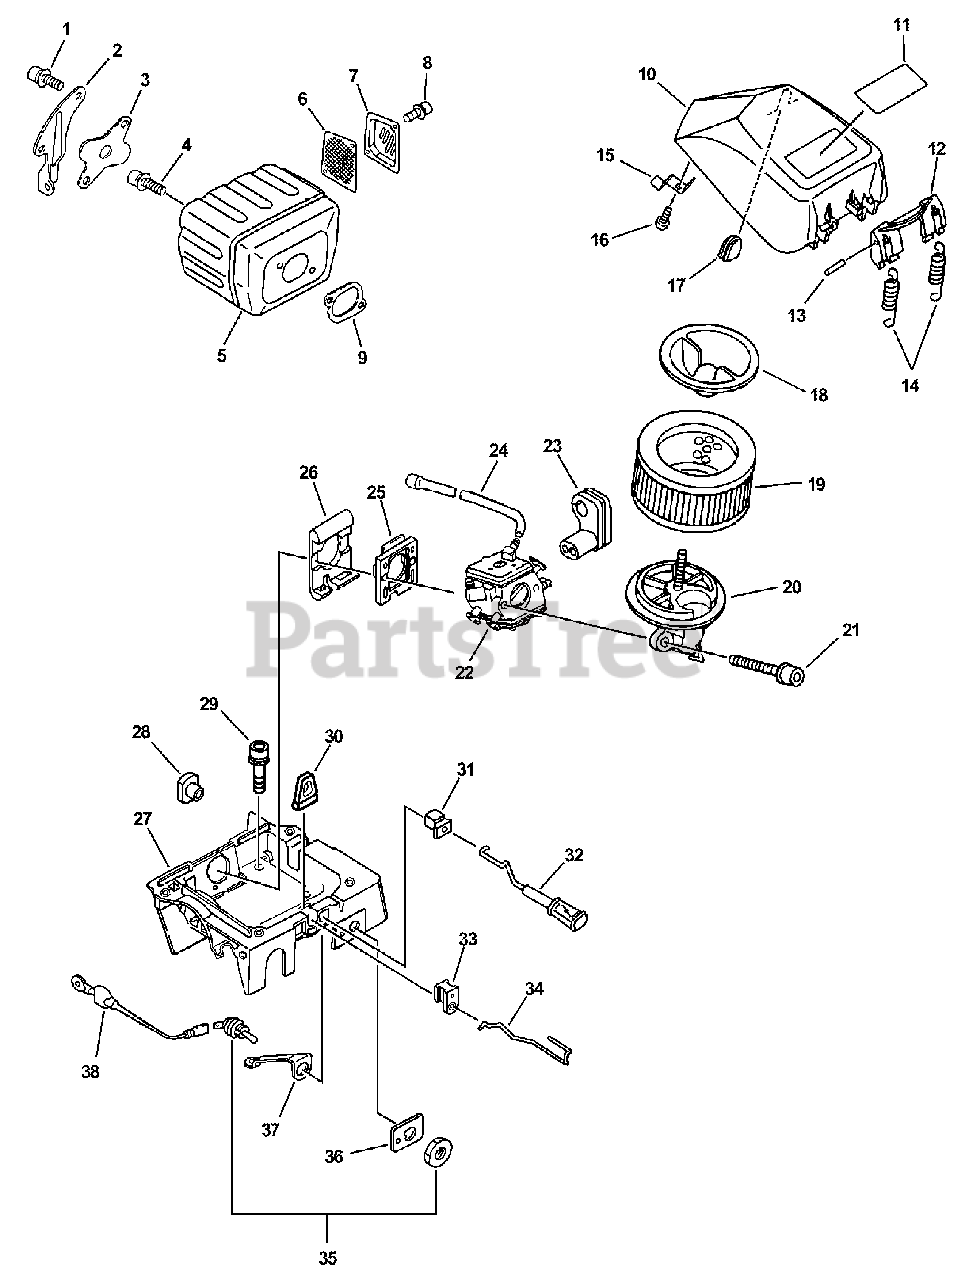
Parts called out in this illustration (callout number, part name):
1	BOLT 5×14
2	BRACKET, MUFFLER
3	COVER, MUFFLER
4	BOLT 5×20
5	MUFFLER
6	SCREEN, SPARK ARRESTER
7	GUIDE, EXHAUST
8	BOLT 4×10
9	GASKET, EXHAUST
10	COVER, AIR FILTER
11	LABEL, MODEL
12	LATCH, FILTER COVER
13	PIN 3×12
14	SPRING, TENSION
15	SPRING, FLAT
16	SCREW 4×10
18	COVER, AIR FILTER
19	FILTER, AIR
20	MOUNT, AIR FILTER
21	BOLT, FLANGE
22	CARBURETOR
23	GROMMET, NEEDLE
24	PIPE, IMPULSE
25	INSULATOR, INTAKE
26	CUSHION
27	CASE, CARBURETOR
29	BOLT 5×20
30	CUSHION
31	GROMMET, CHOKE
32	ROD, CHOKE
33	GROMMET, THROTTLE ROD
34	ROD, THROTTLE
35	SWITCH, ON-OFF
36	LABEL, STOP
37	PLATE, GROUND
38	LEAD
